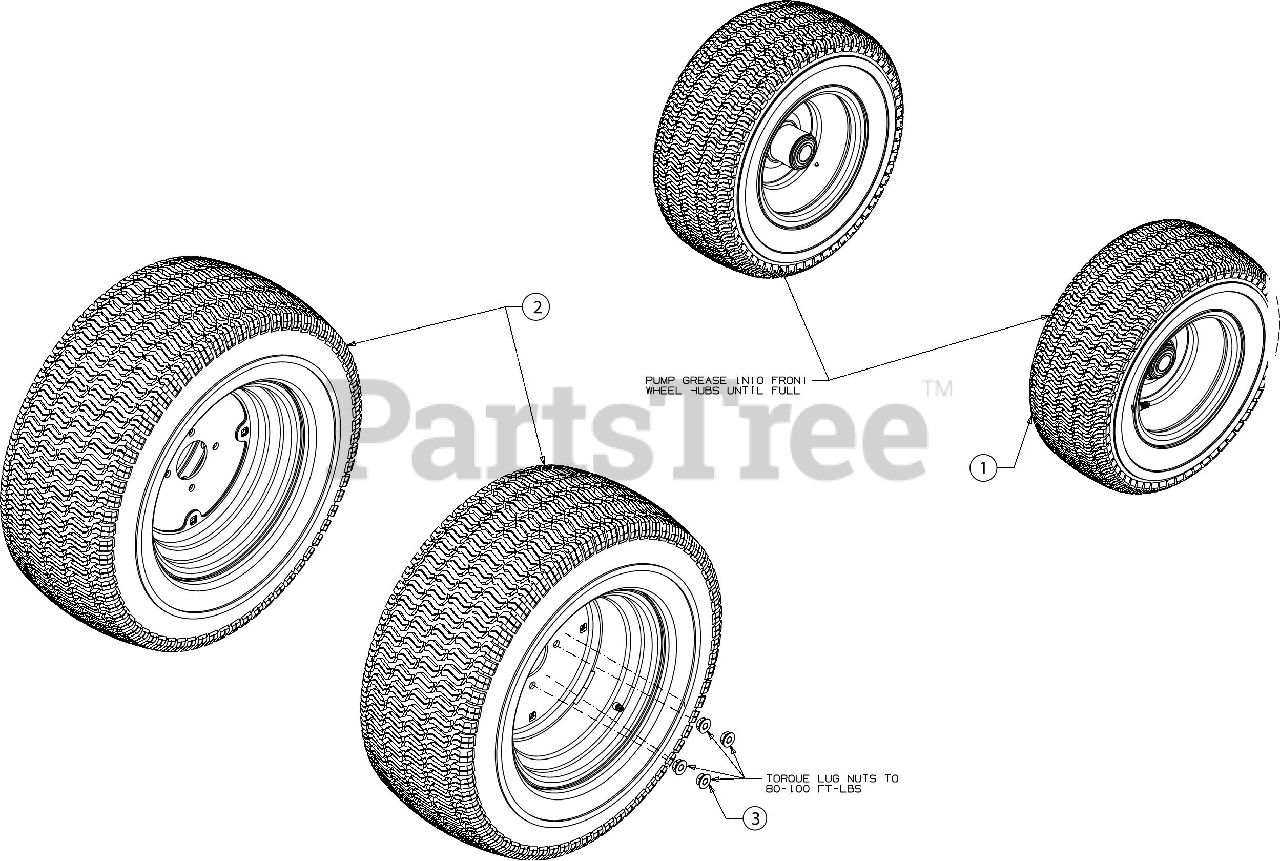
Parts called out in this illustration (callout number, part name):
1	WHEEL ASSEMBLY (16X6.5X8)
2	WHEEL ASSEMBLY (23X10.5X12)
3	LUG NUT 7/16-14
